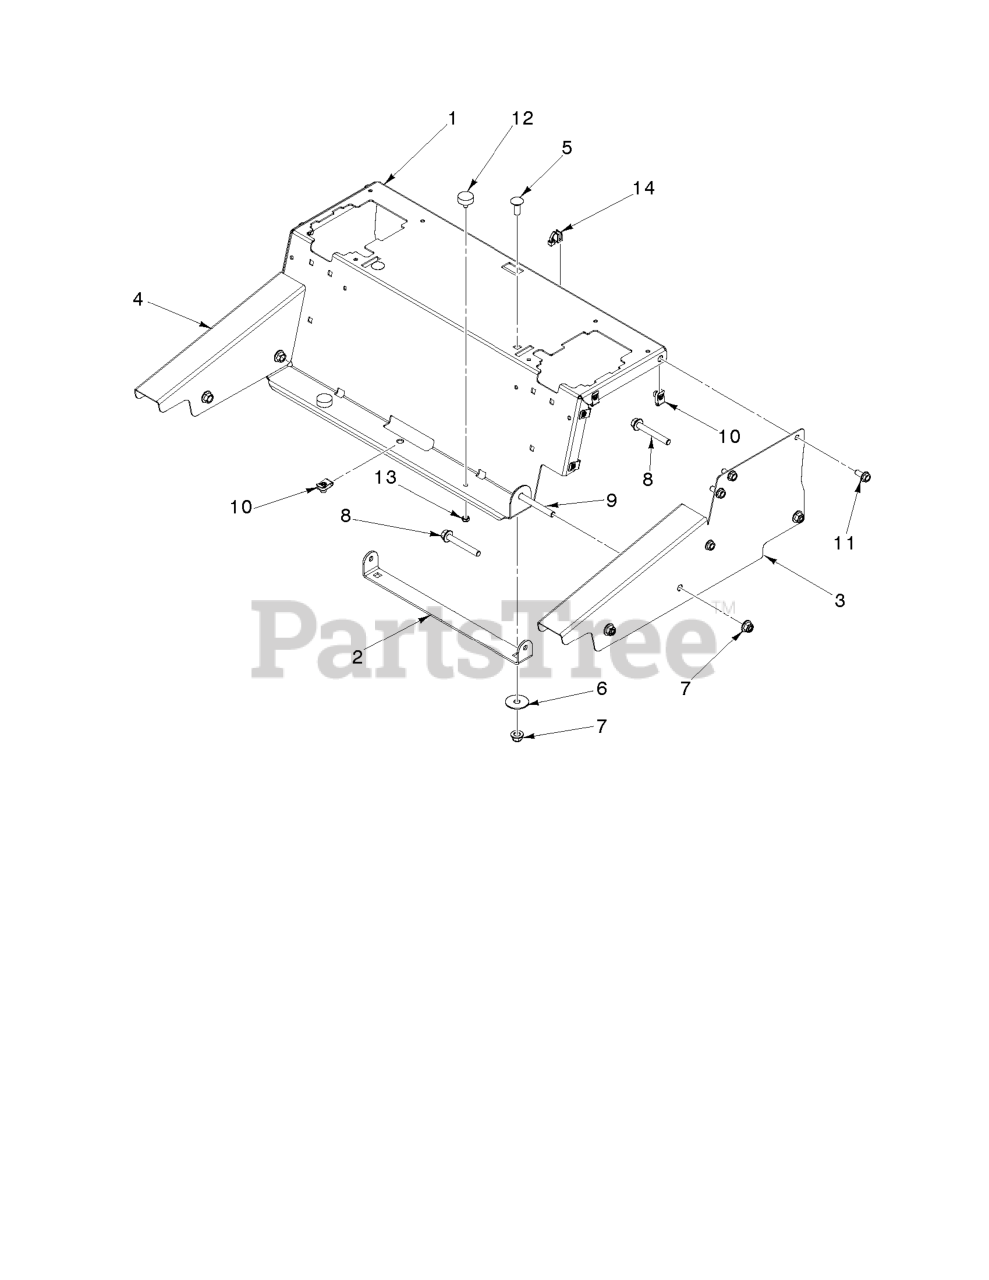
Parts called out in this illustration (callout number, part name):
1	Supports
1	SUPPORT.SEAT.DECK.W/HOLES.ORN
2	Brackets
3	Plates
4	Plates
5	Bolts
6	Washers
7	GSPW Nuts
8	Screws
9	Hardware
10	U-CLIP 5/16-18 NUT RETAINER
11	Bolts
12	BUMPER, 1/4-20 STUD, 1/4
13	Hardware
14	Clips
